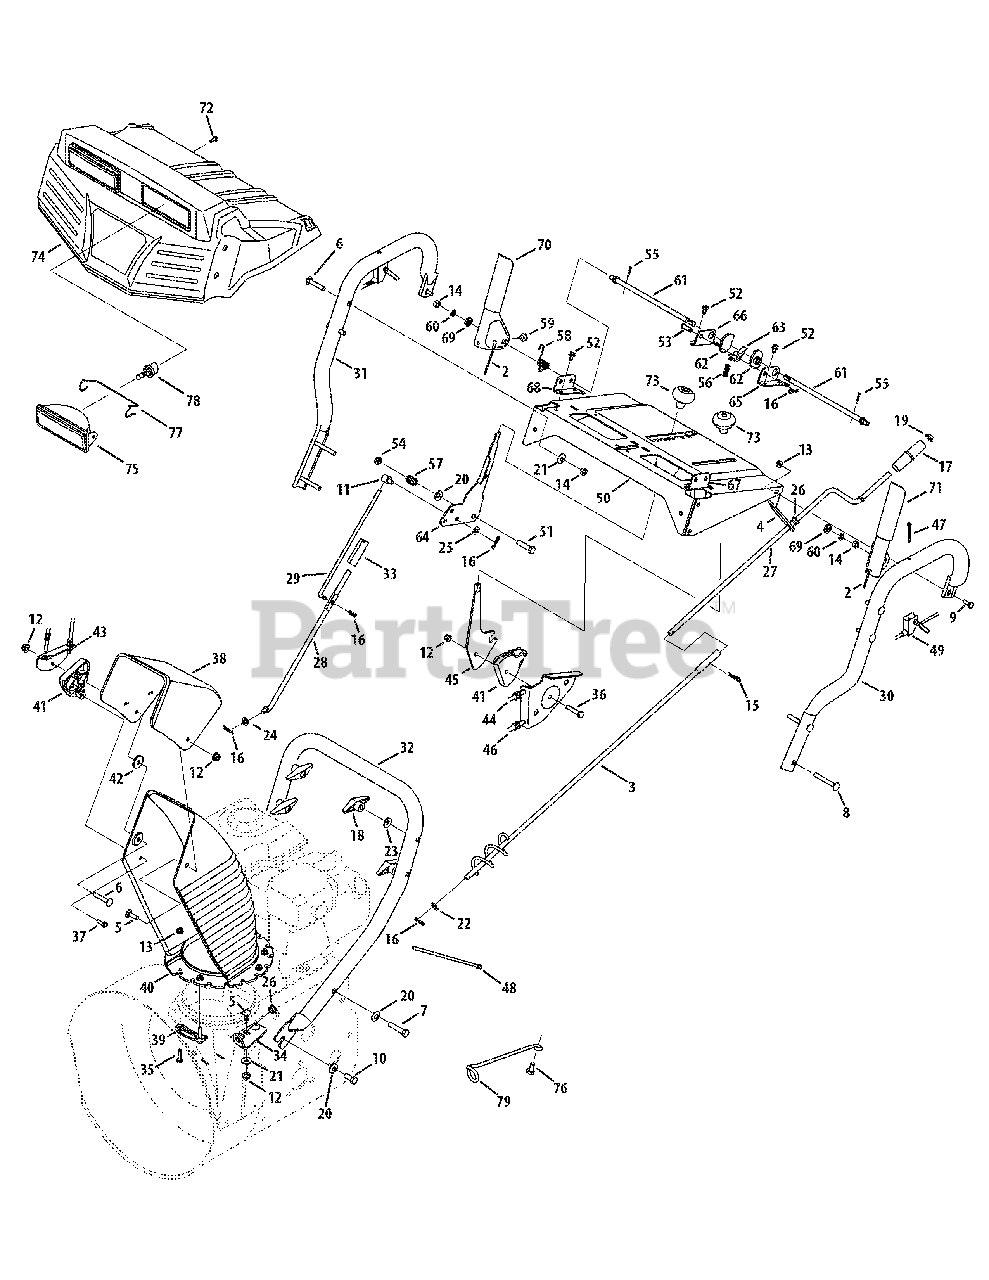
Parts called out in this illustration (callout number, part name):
1	Duel Light Harness
2	Cable Assembly, Auger/Drive
5	Screw, Carriage, 5/16-18 x 1.0
6	Screw, Carriage., 5/16-18 x 1.75
7	Screw, Hex Lock, 3/8-16 x 2.0 Gr5
8	Screw, Carriage., 5/16-18 x 2.5
9	Screw, Hex, 1/4-20 x .75
10	Screw, Hex Lock, 3/8-16 x 1.0 Gr5
11	Ferrule, 5/16-18 x .312 Dia
12	Nut, Flange Lock, 5/16-18
13	Nut, Hex Flange, 1/4-20
14	Nut, Hex Patch Lock, 5/16-18 Gr5
15	Pin, Internal Cotter
16	Pin, Internal Cotter
17	Knob, Crank
18	Knob, Wing Nut, 5/16-18
19	Cap, Push, 3/8
20	Washer, Bell, .375 x .87 x .063
21	Washer, Flat, .349 x .879 x .063
22	Washer, Flat, .375 x .738 x .063
23	Washer, Bell, .34 x .872 x .06
24	Washer, Flat, .344 x .688 x .065
25	Washer, Flat, .344 x .750 x .120
26	Bushing, Plastic, .38 ID
28	Rod, Lower Shift
29	Rod, Upper Shift
33	Connector, Shift Rod
35	Screw, Hex, 1/4-20 x 1.0
36	Screw, Hex, 5/16-18 x 1.5
37	Screw, Hx,1/4-15 x .75
38	Chute, Upper, 6.0
39	Flange Keeper, Chute
40	Chute, Lower
41	Cbl. Guide, Chute Tilt
42	Washer, Flat, .344 x 1.125 x .12
44	Cable, Chute Control, 66"
46	Cable, Chute Control w/Clip,
47	Screw, #10-24 x 1.75
48	Tie, Cable
49	Cable Assembly, Trigger
51	Screw, Hex, 3/8-24 x 1.5
52	Screw, Hex, 1/4-20 x .5
53	Pin, Clevis, .312 x 1.0
54	Nut, Insert, 3/8-24
55	Pin, Cotter, 3/32 x .75
56	Spring, Compression
57	Spring, Compression
58	Spring, Torsion
59	Bumper, Rubber
60	Washer, Lock, 5/16
62	Cam, Handle Lock
63	Pawl, Handle Lock
69	Washer, Flat, .35 Sq x .72 x .134
70	Handle, Engage, RH
71	Handle, Engage, LH
72	Screw, #10-16 x .625
73	Knob, Shift
74	Panel, Handle
75	Lamp Housing Assembly w/ Lens
76	Screw, 5/16-18 x .750
77	Headlight Retainer
78	Lamp, Halogen, #890-12V-27W
79	Cable Guide
